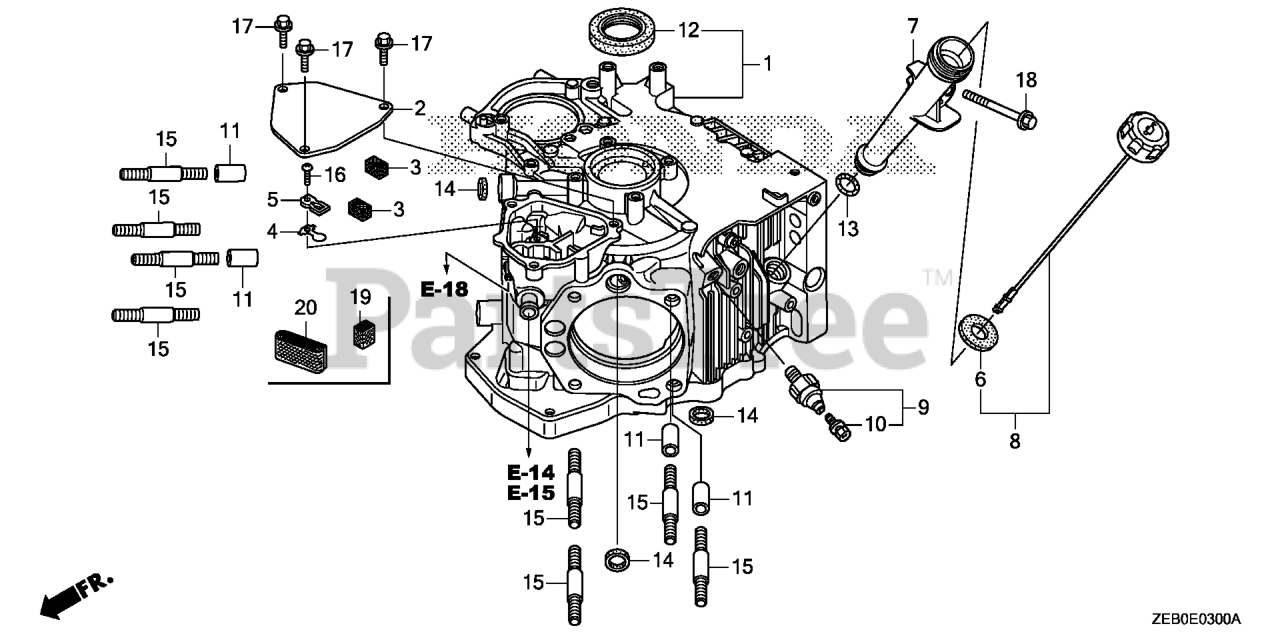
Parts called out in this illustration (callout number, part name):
1	CRANKCASE ASSY.
2	COVER, BREATHER
4	VALVE, OIL OUTLET
5	PLATE, STOPPER
6	GASKET, OIL FILLER CAP
7	EXTENSION, OIL FILLER
8	GAUGE ASSY., OIL LEVEL
9	SWITCH, OIL PRESSURE
10	SCREW-WASHER (4X8)
11	PIN, DOWEL (12X20)
12	OIL SEAL (38X58X9)
13	O-RING (14.8X2.4)
14	GASKET, OIL PASSAGE
15	BOLT, STUD (10X40)
16	SCREW, PAN (3X8)
17	BOLT, FLANGE (6X14)
18	BOLT, FLANGE (6X45)
19	FILTER, BREATHER
20	FILTER, BREATHER (NA USE ALT:12367-Z6M-000)
